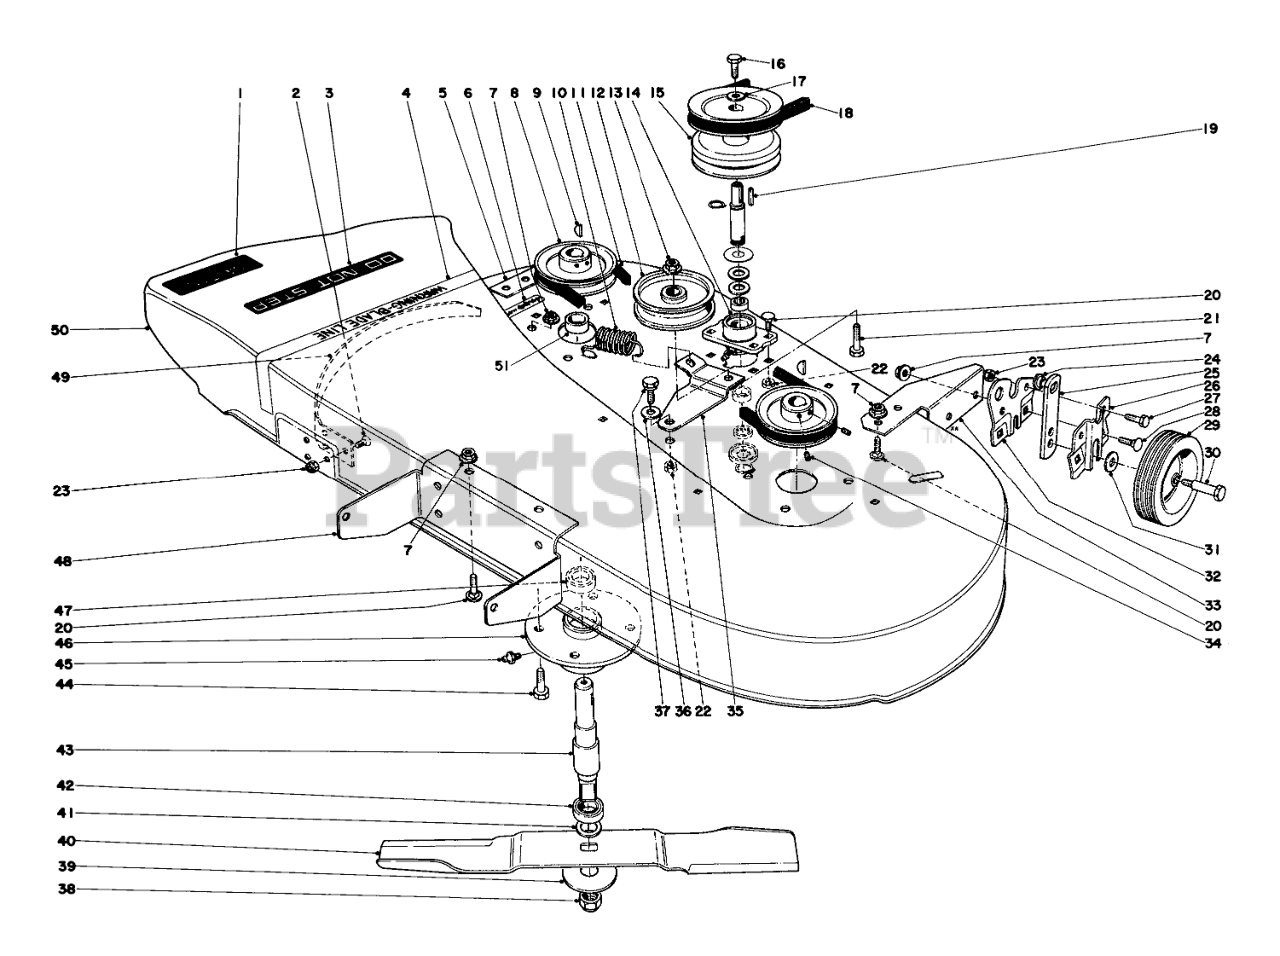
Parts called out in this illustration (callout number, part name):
1	Decal
2	SCREW-HSFH
3	Decal
4	Decal-Blade Line
5	Rear Bracket R.H.
6	Decal Height of Cut
7	NUT-HF
8	Pulley
9	KEY-WOODRUFF
10	Idler Lever Spring
11	V-Belt
12	Flat Idler
13	NUT-LOCK, SIDE
14	Housing, Idler
15	Double Pulley
16	SCREW-HH
17	Washer
18	V-Belt
19	KEY-SQUARE
20	BOLT-CARR
21	SCREW-HH
22	NUT-LOCK, CONE
23	NUT-LOCK, CONE
24	Bushing
25	HEIGHT ADJ SLIDE
26	Retainer, Height Adj.
27	SCREW-HH
28	SCREW-CARR
29	Wheel
30	Screw
31	Washer
32	Bracket R. H.
33	Rear Bracket L.H.
34	5/16-18 X 1/2 SQ HD
35	Idler Lever
36	Washer
37	Screw
39	WASHER
40	Blade
41	WASHER
42	.6693 RP BALL BEARING
43	BLADE SPINDLE
44	SCREW-HH
45	FITTING-GREASE
46	Housing Mower Spindle
47	Bearing
48	Front Bracket
49	Deflector Bar
51	Blade Spindle Spacer
